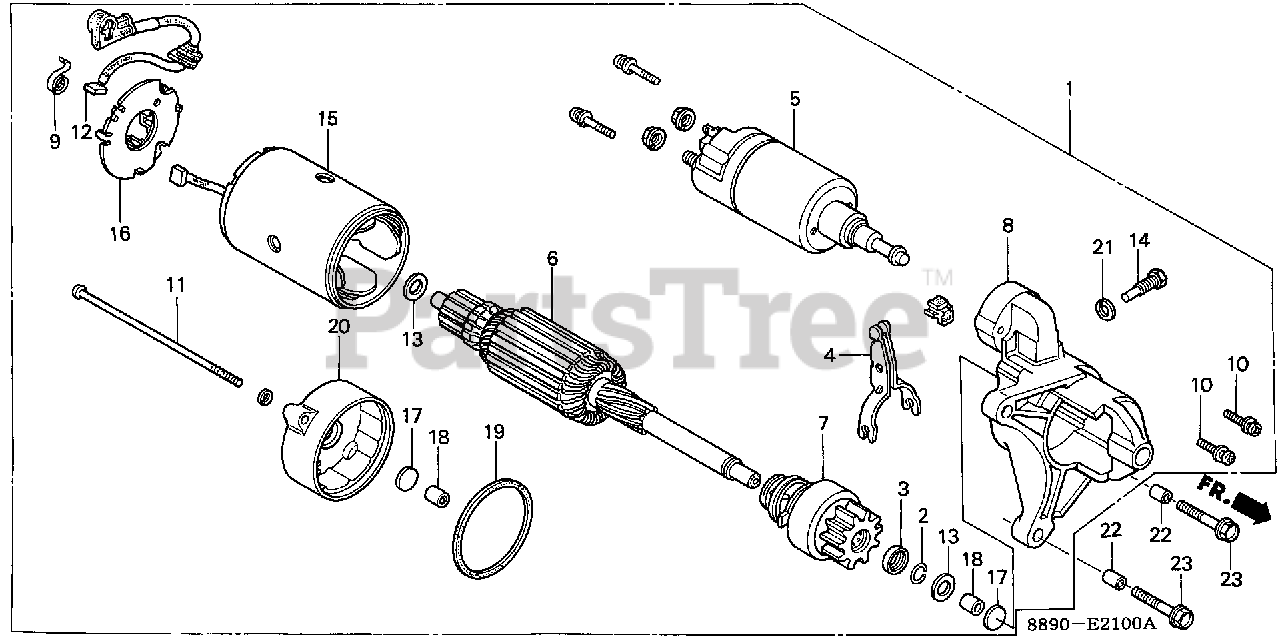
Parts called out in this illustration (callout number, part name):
1	STARTER MOTOR ASSY.
2	RING, SNAP (NOT AVAILABLE)
3	COLLAR, CLUTCH STOP
4	LEVER, PINION DRIVE (NOT AVAILABLE)
5	SWITCH, MAGNETIC (NOT AVAILABLE)
6	ARMATURE (NOT AVAILABLE)
7	PINION
8	CASE, GEAR
9	SPRING, BRUSH (NOT AVAILABLE)
10	SCREW, MAGNETIC SWITCH SETTING
11	BOLT, THROUGH (NOT AVAILABLE)
12	BRUSH (NOT AVAILABLE)
13	WASHER
14	SCREW, POLE CORE SETTING
15	COIL, FIELD
16	HOLDER, BRUSH
17	COVER, BEARING
18	BUSH, BEARING
19	GASKET, RUBBER PLATE
20	COVER, RR.
21	WASHER, SPRING (8MM)
22	PIN, DOWEL (10X16)
23	BOLT, FLANGE (8X35)
